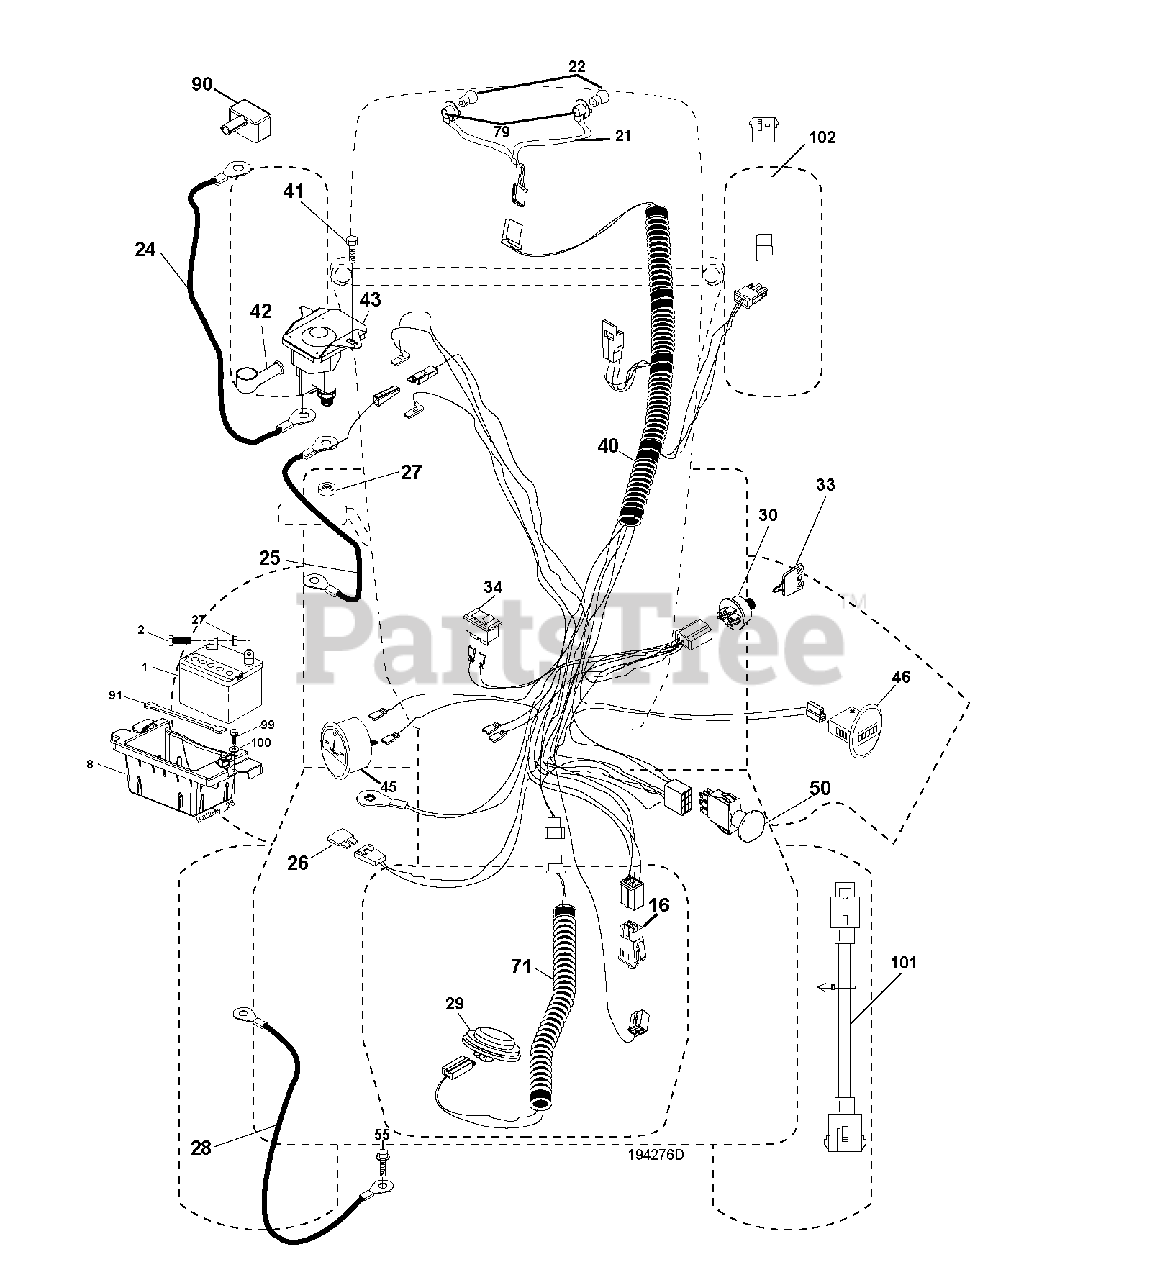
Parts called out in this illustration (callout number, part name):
1	BATTERY 12V .35 AMP
8	BOX.BATTERY.MOUNT.FRONT.LT
16	SWITCH INTERLOOK PUSH-IN
21	HARNESS.W/LIGHT SOCKET
22	LIGHTBULB
24	CABLE.BATT.POS.WIRE.TG.DA SOL
25	CABLE.START.RED.17.5".
26	FUSE 20AMP
27	NUT
28	CABLE GROUND 6 GA 21" 90T BLK
29	SWITCH.SEAT.DELTA.OPC.
30	SWITCH.IGN.DELTA.W.LGH.ROS
33	KEY MLD GEN DELTA
34	SWITCH LT
40	HARNESS IGN. DASH
41	SCREW
42	TERMINAL COVER
43	SOLENOID.W/BRASS.PLUNG
46	HOURMETER SNAP-IN
50	PTO SWITCH
55	SCREW 5/16"
71	HARNESS-CHASSIS SUB
79	BULB HOLDER ASM.
90	COVER.TERMINAL.BATTERY
91	STRAP, BATTERY MOUNT
99	SCREW HEXWSHR 1/4-20X3/4
100	WASHER
101	PIGTAIL.MATNLK.NEW.HAR
102	HARNESS PIGTAIL PCH TEX ROS
